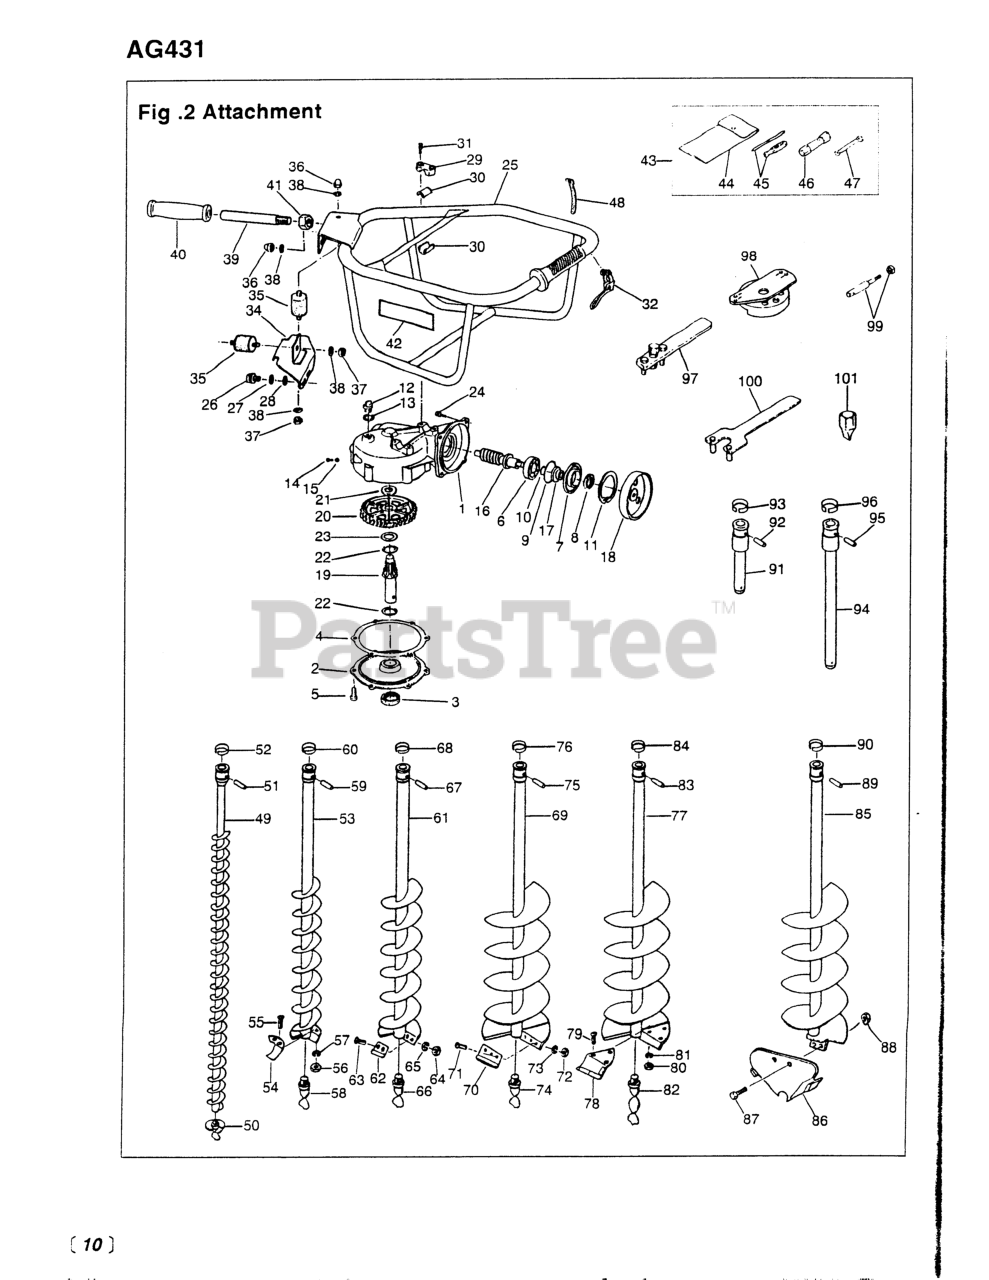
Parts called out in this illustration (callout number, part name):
1	GEARCASE COMP (RPLS -11102)
2	COVER COMP (RPLS -11202)
3	SEAL, OIL
4	GASKET
7	RETAINER
9	O-RING
11	RING, SNAP, M62 x 2.0
14	BOLT, M6 x 10
19	SHAFT
24	BOLT, M6 X 20
25	HANDLE
28	WASHER, M6 X 2.3
30	SPACER
31	BOLT, M6 x 30
32	LEVER, THROTTLE
37	NUT, M6 X 5
38	WASHER, M6 X 15
39	HANDLE COMPLETE
40	GRIP (REPLACES -14220)
41	NUT, M14 x 11
43	TOOL SET
45	SCREWDRIVER
47	SPANNER, 8 X 10 (RPLS 2540- )
48	BAND
49	S40 DRILL ASS
51	PIN
52	CLIP
53	DRILL S60 ASS
55	SCREW, M6 X 20
56	NUT, M6 X 5
57	WASHER, M6 X 15
58	BIT
59	PIN
60	CLIP
61	S90 DRILL ASS
62	TIP, S90
63	SCREW, M6 X 20
64	NUT, M6 X 5
65	WASHER, M6 X 15
66	BIT
67	PIN
68	CLIP
69	S150 DRILL ASS
70	TIP, S150
71	SCREW, M6 X 20
72	NUT, M6 X 5
73	WASHER, M6 X 15
74	BIT
75	PIN
76	CLIP
77	S200 DRILL ASS
78	TIP, S200
79	SCREW, M6 X 20
80	NUT, M6 X 5
81	WASHER, M6 X 15
82	BIT
83	PIN
84	CLIP
85	I150 DRILL ASS
87	BOLT, M6 X 20
88	NUT, M6 X 5
89	PIN
90	CLIP
91	JOINT L100 ASS
92	PIN
93	CLIP
94	JOINT L300 ASS
95	PIN
96	CLIP
98	SET BLOCK (TOOL)
99	ROD ASSEMBLY (TOOL)
NI	BRACKET ASSY (RPLS-31201)
